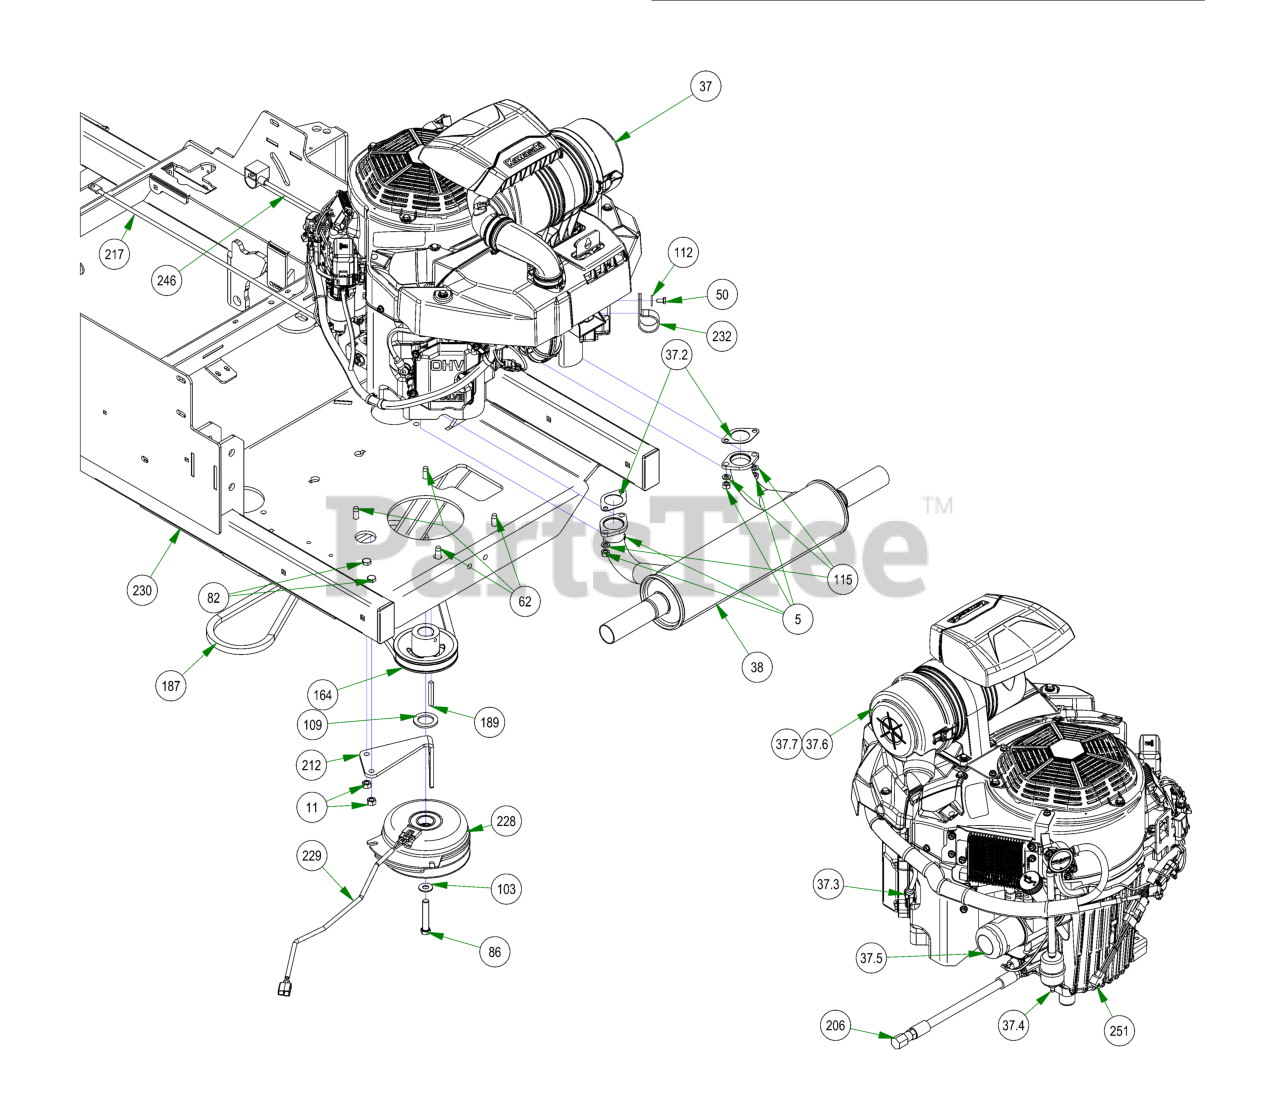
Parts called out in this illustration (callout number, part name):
5	M8-1.25 DIN 934 HEX NUT (CL.8) ZINC
11	3/8-16 HEX NUT ZINC
31	1 1/2 x 3 Frame Plug
37	Kawasaki FX1000 Engine
37.2	Exhaust Gasket
37.3	Spark Plug - Kawasaki
37.4	Universal Inline Fuel Filter
37.5	Oil Filter
37.6	Canister Air Filter- Outer
37.7	Canister Air Filter- Inner
38	2019 Rebel/Rogue Kawasaki 1000 Muffler
50	M6-1.0 X 12MM DIN 933 HEX TAP BOLT (CL 8.8) ZINC
62	3/8-16 X 1-1/8HEX WASHER UNSLOT SERRATED
82	3/8-16 X 1-1/4 HEX CAP SCREW (GR.5) ZINC
86	7/16-20 X 2-1/2 HEX Bolt GR 8 W/ Patch
103	3/8 FLAT WASHER USS (1" OD) ZINC
109	1.140 ID X 1.750 OD X .132 THICK FLAT WASHER PLAIN
112	1/4 USS FLAT WASHER (3/4 OD) ZINC
115	5/16 SPLIT LOCKWASHER ZINC
164	4 3/4 Motor Pulley
187	2019 Rogue Pump Belt 68"
189	1/4 X 2 SQ MACHINERY KEY 1018 STL PLAIN
206	Kawasaki Oil Drain
212	PTO Engager Holder
217	24" Red Battery Cable
228	Clutch Assembly
229	Clutch Pigtail
230	2021 Rogue Suspension Frame Painted
232	Diesel Hydraulic Hose Clamp
246	Starter Cable
251	2022 Harness Adaptor- EFI
